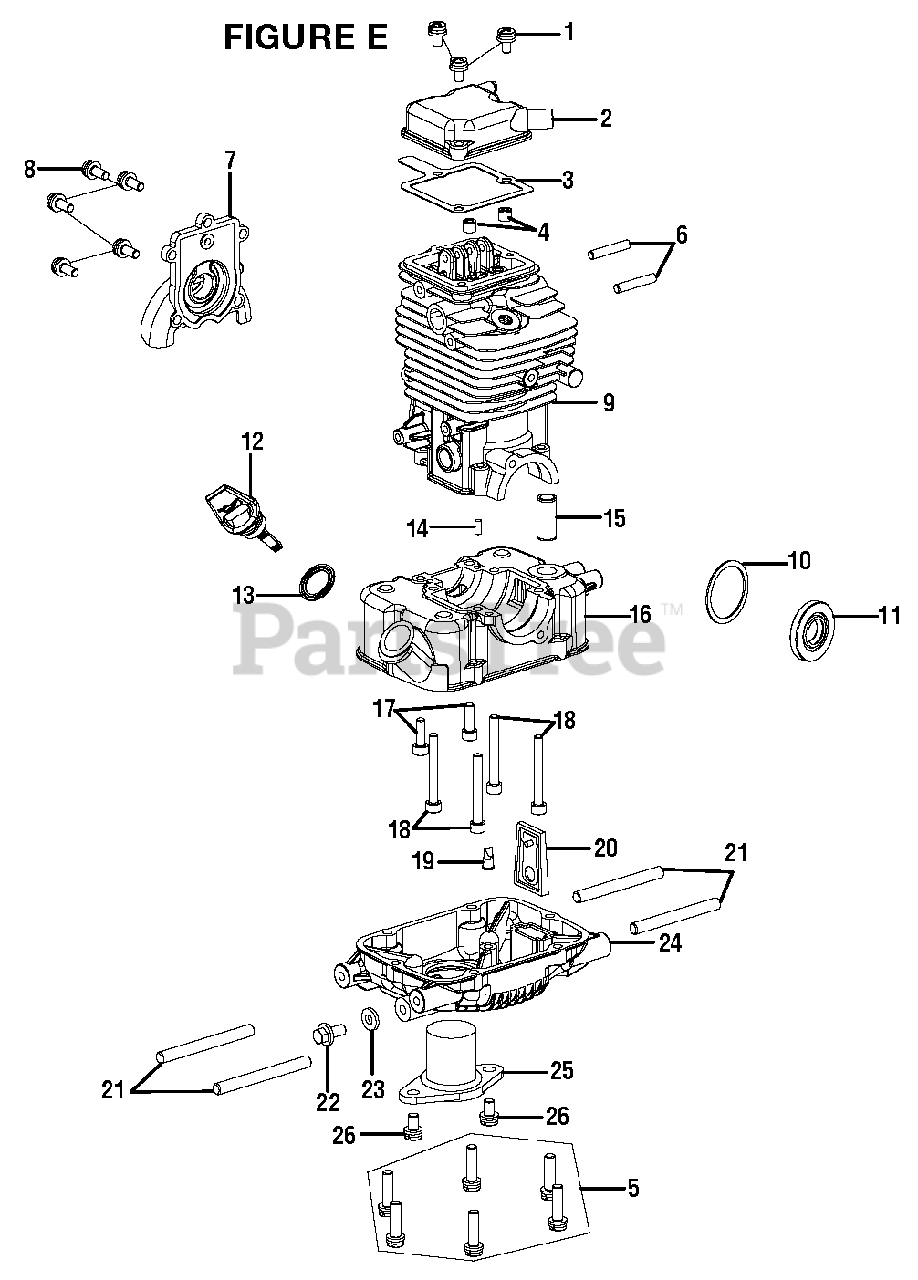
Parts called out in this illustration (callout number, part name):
1	Screw (M5 x 20 mm)
2	Cylinder Head Cover
3	Cylinder Head Cover Seal
4	Valve Oil Seal
5	Dual-Head Bolt (M5 x 25 mm)
6	Dual-Head Bolt (M5 x 28 mm)
8	Screw (M5 x 14 mm)
9	Upper Crankcase
10	Washer (ID30 x OD37 x 1t)
13	Oil Gauge Gasket
15	Ventilation Nozzle
16	Lower Crankcase
17	Screw (M5 x 16 mm)
18	Screw (M5 x 40 mm)
20	One-Way Valve Component
21	Dual-Head Bolt (M6 x 36 mm)
22	Bolt (M6 x 12 mm, Flange Hex Hd.)
23	Aluminium Gasket
25	Oil Level Sensor
26	Screw (M6 x 18 mm)
